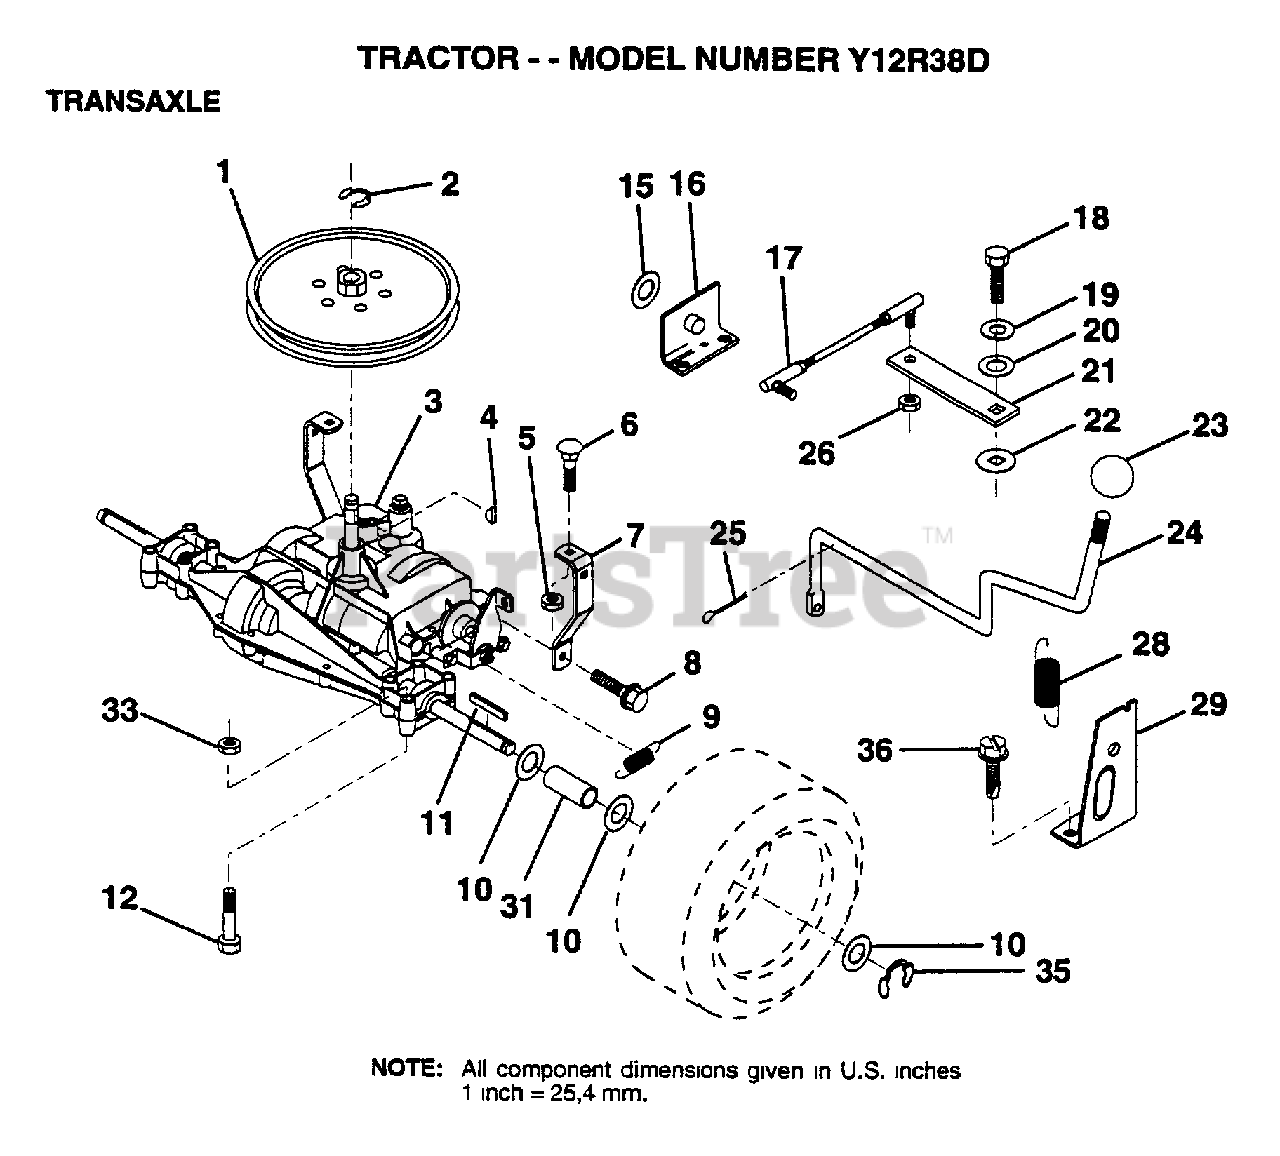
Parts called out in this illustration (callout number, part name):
1	PULLEY
6	BOLT
7	"STRAP,TORQUE"
8	SCREW
9	SPRING.BRAKE.RETU
10	WASHER
11	SQUARE KEY
12	BOLT
16	"SUPT,HDLE SHT LH"
17	"LINK,SHIFT"
18	BOLT.1/4-28.W/PAT
19	LOCKWASHER
20	WASHER LT
21	"ARM,SHIFT"
22	WASH-SHFT PLT LT
23	KNOB.DUCKHEAD.1/2
24	"ROD,SHIFT"
25	PIN COTTER 1/8
26	NUT.LOCK.5/16-24
28	"SPRING,EXT"
29	"SUPT,HDLE RH"
31	SPACER LT
35	E-RING LT
36	SCREW
